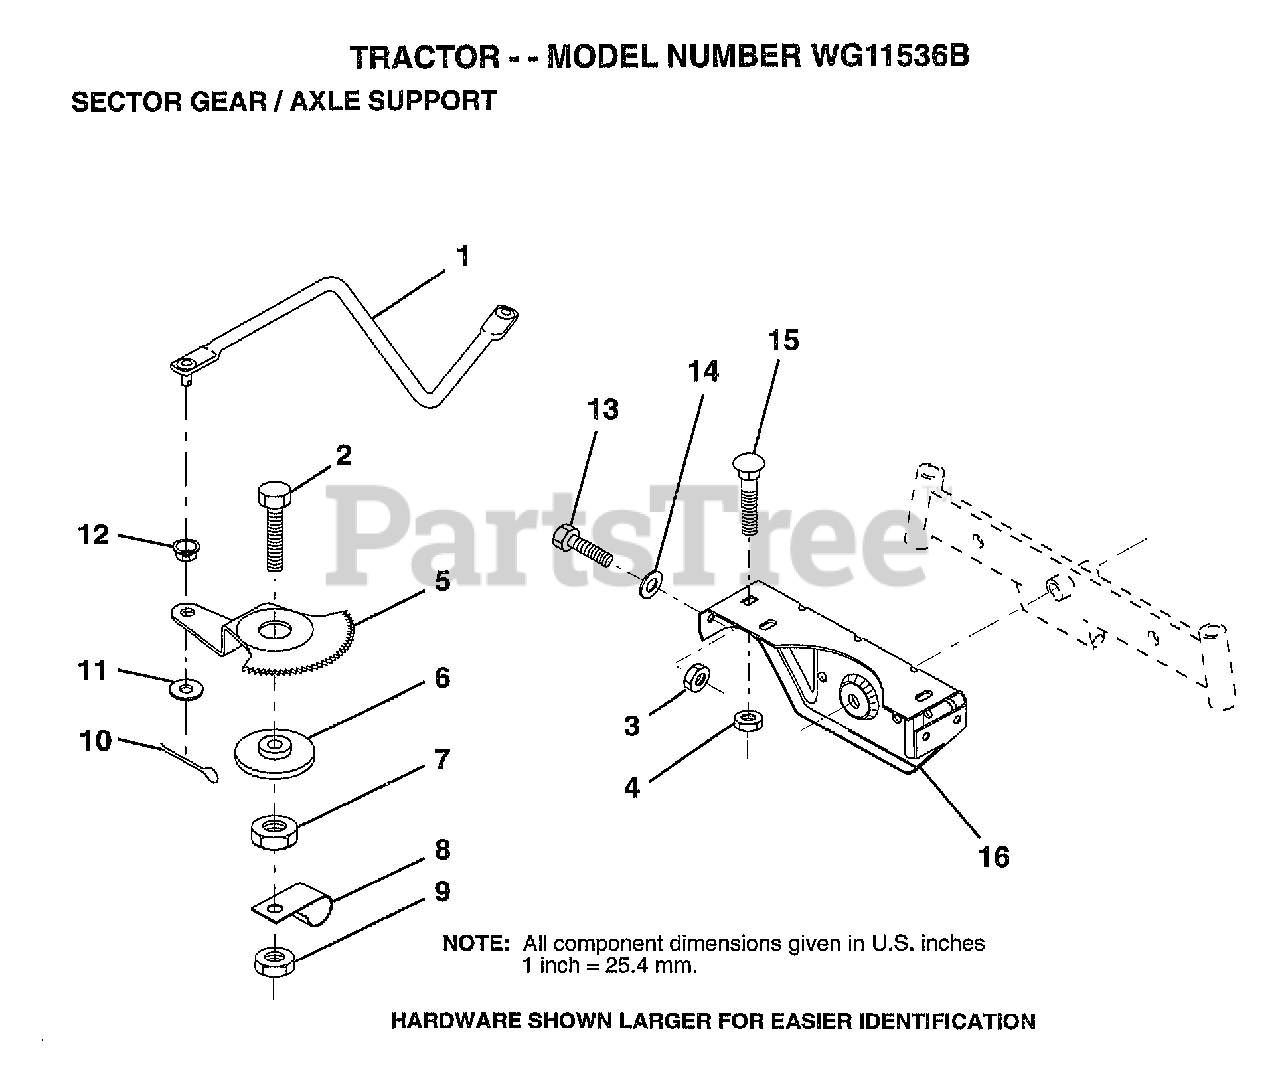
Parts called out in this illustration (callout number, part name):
1	DRAG LINK
2	"BOLT,HEX"
5	GEAR SECTOR
6	BUSHING
7	NUT
8	CLIP INSULATOR
9	NUT LTV
10	COTTER PIN
11	WASHER
12	BUSHING.DRAGLINK
13	BOLT
14	WASHER
15	BOLT
16	SUPT AXLE FRONT
